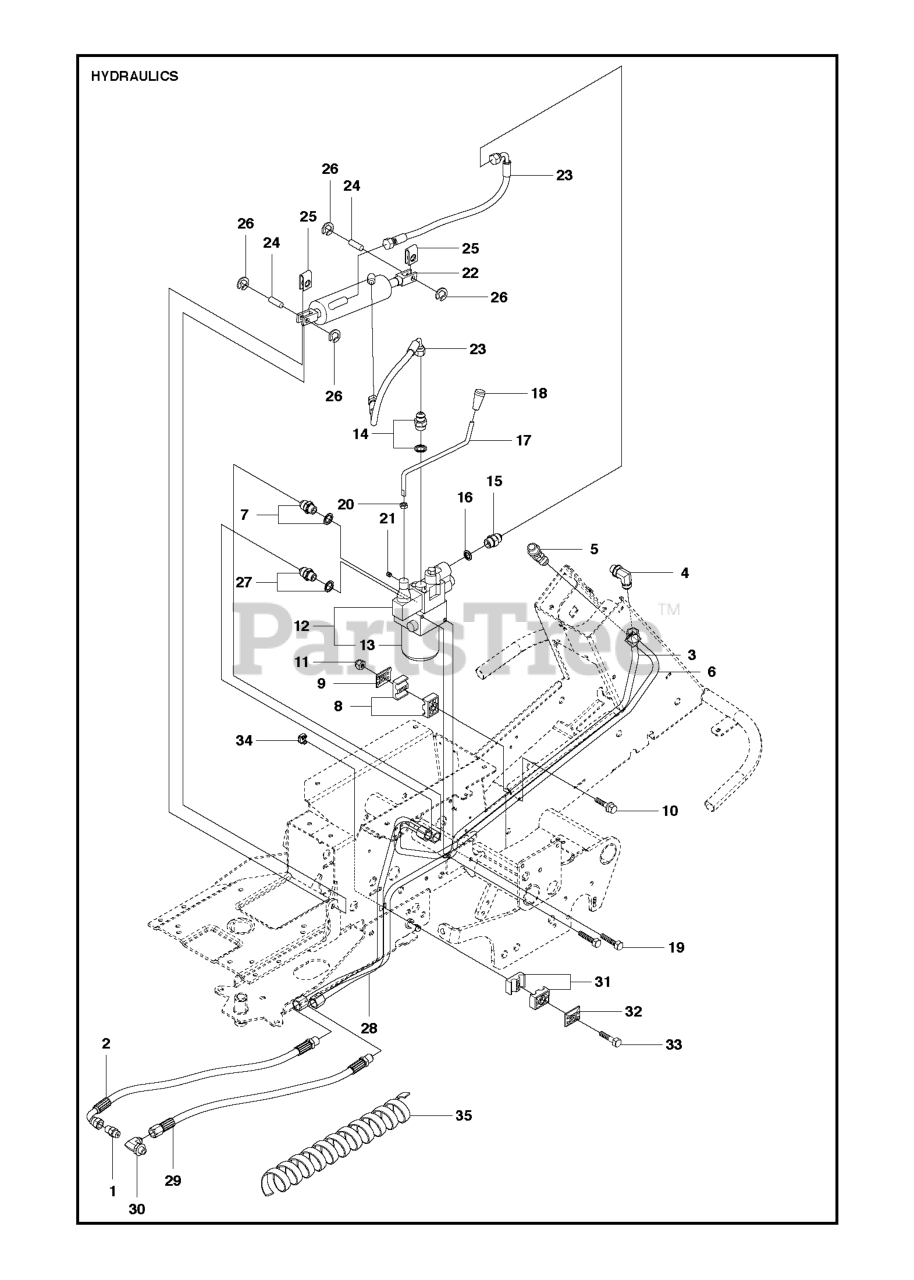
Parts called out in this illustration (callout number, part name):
8	PIPE CLAMP
11	LOCKNUT M6
13	FILTER
19	REPL BY 725 24 49-51
20	NUT
26	RETAINING RING SGA 10
31	PIPE CLAMP
